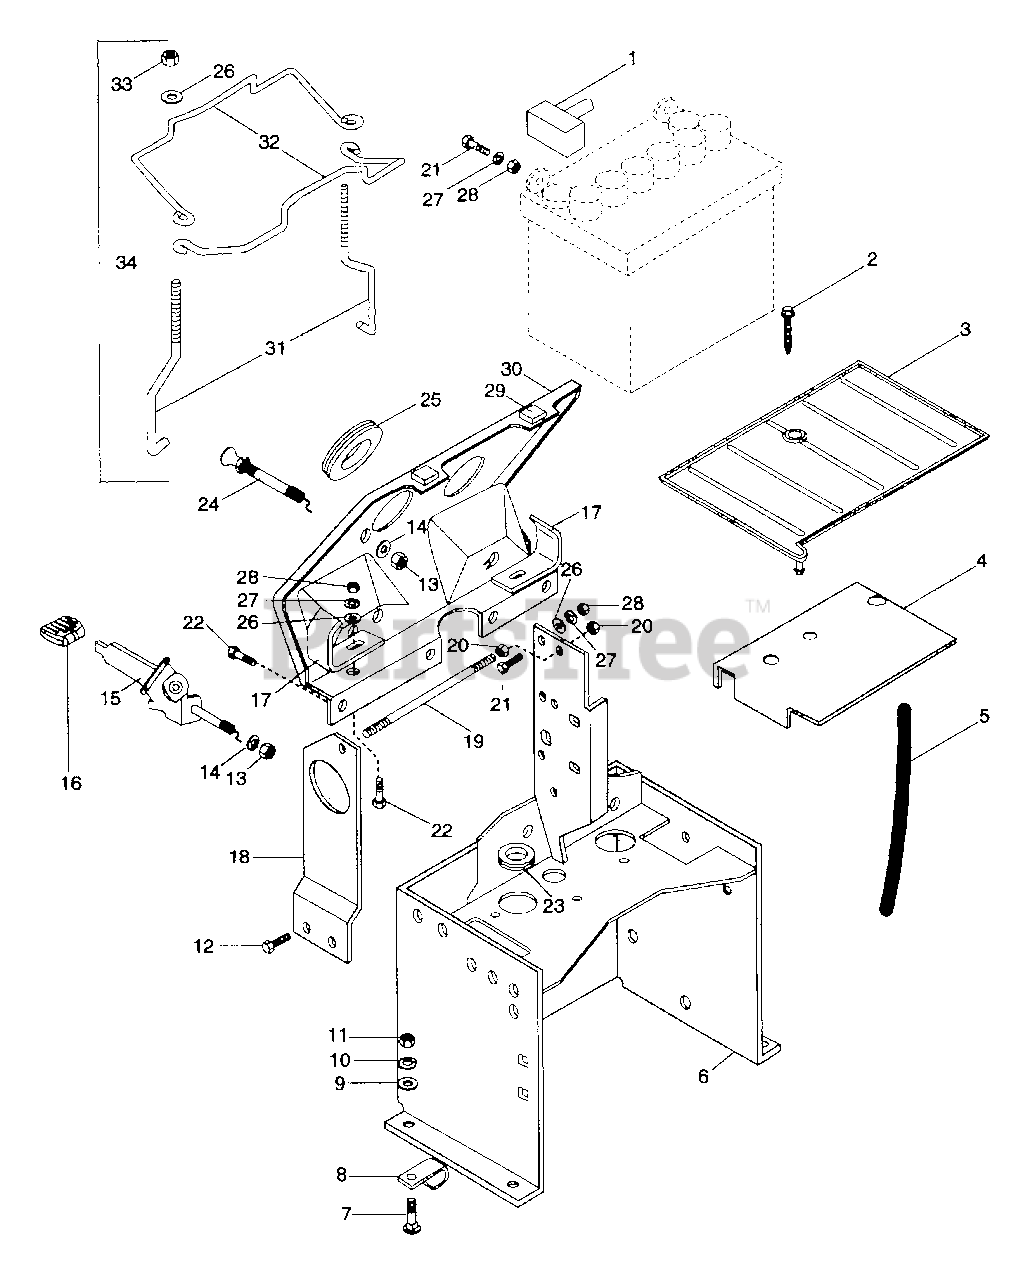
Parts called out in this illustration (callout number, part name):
1	INSULATOR
2	SCR-TAP 12-14X1.50 CROVH PL BT
3	BATTERY TRAY
4	BATTERY STAND
5	DRAIN HOSE
6	DASH SUPPORT PS
7	BLT-RDHDSQNK .31-18X.75 GR5 PL
8	J-CLAMP
9	WSHR-FL-STL.344X.688X.065PL
10	WSHR-LK .312X.097 PL HVY
11	NUT-HEX .312-18
12	SCR-TAP .250-20X.50 HXSLHDPL
13	NUT-HEX 10-24 PL
14	WSHR-LK-EXT #10 ID X .022
15	THROTTLE CONTROL
18	HOUR METER MOUNTING PLATE
19	BRACE ROD
20	NUT-LK-FLG .250-20 PL
21	BLT-HEX .25-20X.75 PL GR2
22	SCR-TAP 10-24X.375 HWH PL TR
23	GROMMET 1.0ID X 1.38 OD
24	CHOKE CONTROL
25	GROMMET
26	WSHR-FL-STL.281X.62X.065 PL
27	WSHR-LK .250X.077 HVY PL
28	NUT-HEX .250-20 PL
29	STOP
30	DASH
31	TIE DOWN
32	HOLD DOWN
33	NUT-LK-NYL .250-20 PL
34	BATTERY HOLD DOWN ASSEMBLY
